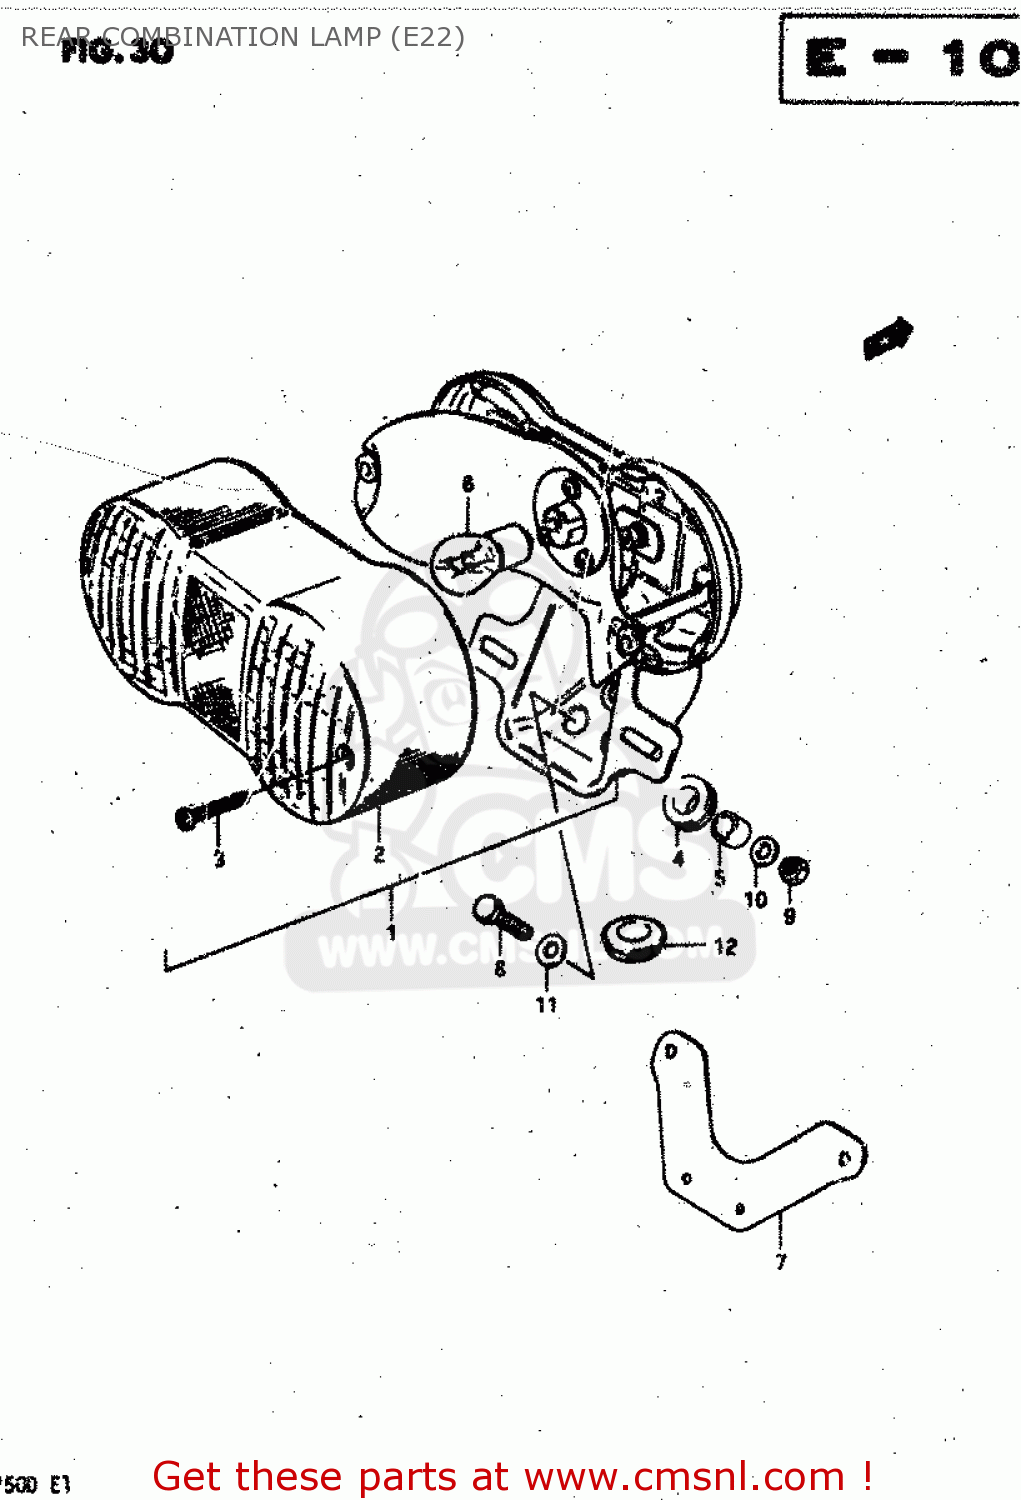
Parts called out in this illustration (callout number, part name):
1	LAMP ASSY, TAIL
2	LENS,RR COMBINATION LAMP
3	SCREW
4	CUSHION
5	SPACER,REAR COMBINATION LAMP
6	BULB (6V,21/5W)
7	FLATE, LICENCE
8	BOLT, UPPER
9	NUT
10	WASHER
11	WASHER (6.5X20X1.2)
12	GROMMET
